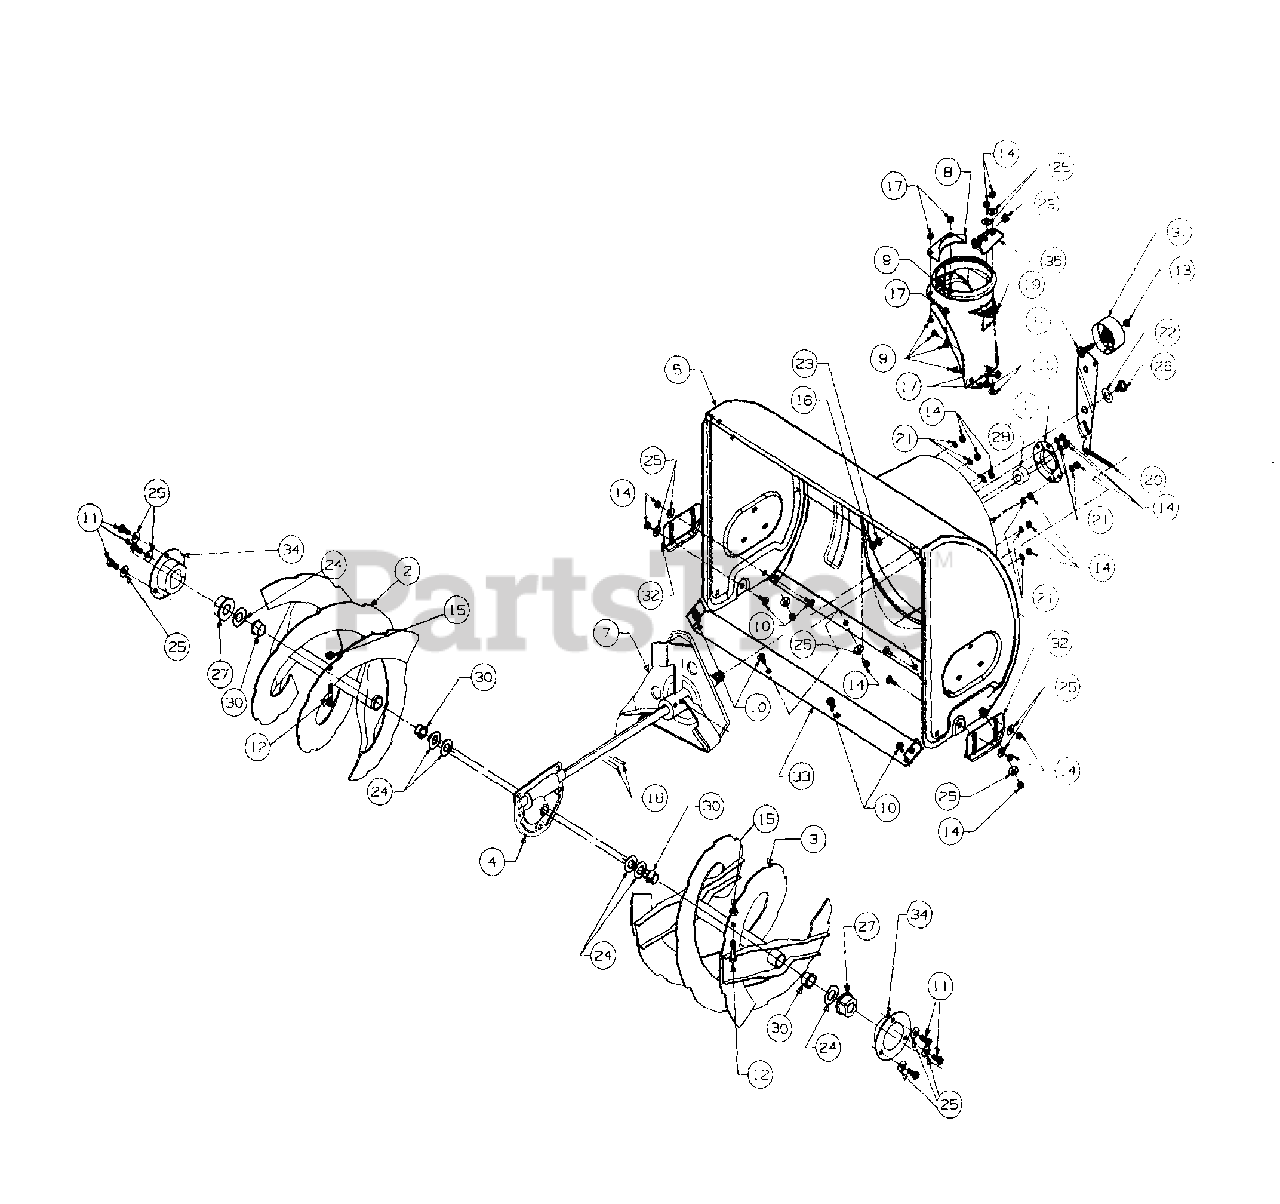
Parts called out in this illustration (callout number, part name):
1	Housing-Bearing
4	Gear Assembly 26"
9	Screw-Carriage
10	Screw-Carriage
11	Screw-Hex
12	Shear Bolt
13	Nut-Hex Lock
14	Nut-Hex
17	Nut-Hex Lock
18	Pin-Spring
19	Adapter-Chute
20	Spring
21	Washer-Lock
22	Washer-Flat
23	Washer-Lock
24	Washer-Flat
25	Washer-Bell
26	Screw-Shoulder
27	Bearing Flange
28	Bearing-Ball
29	Bushing-Plastic
30	Bushing-Flange
31	Idler-Flat
